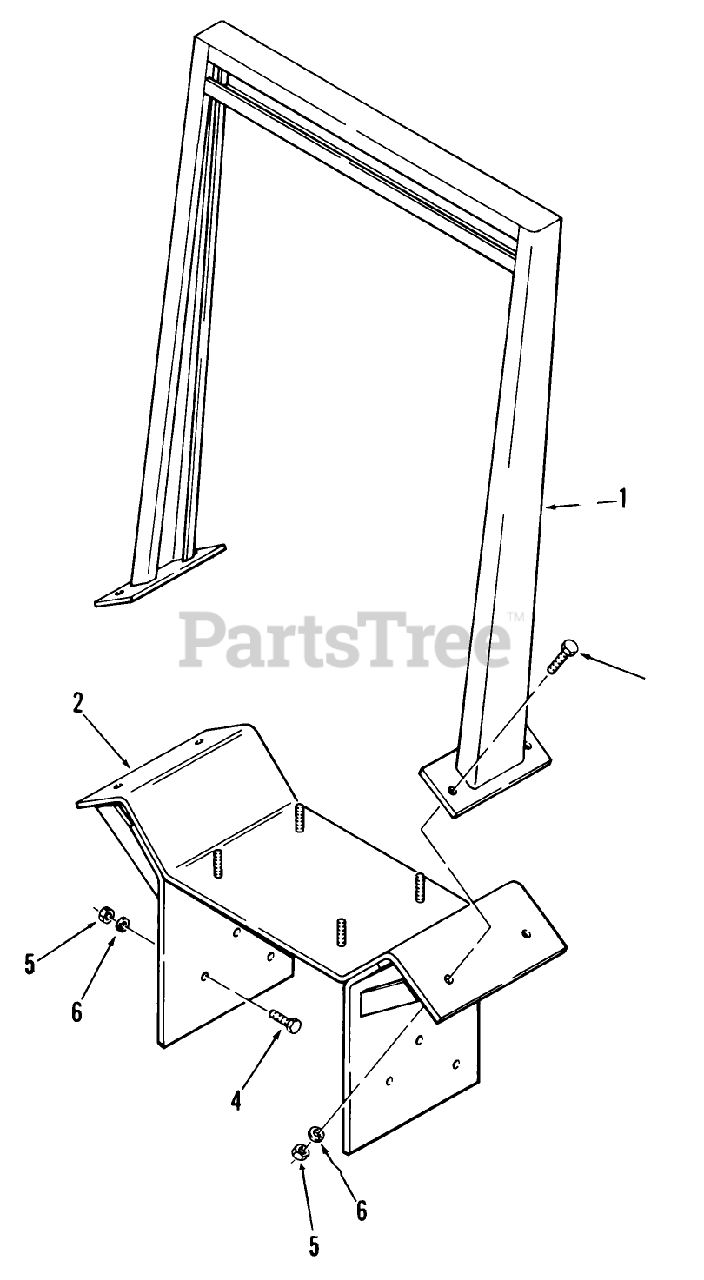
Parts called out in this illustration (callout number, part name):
1	Roll Bar
2	Roll Bar Support
3	Bolt 1/2-13 x 1 3/4 Grade 5
4	Bolt 1/2-13 x 1 1/2 Grade 5
5	Nut 1/2-13 Grade 8
6	Lockwasher 1/2
